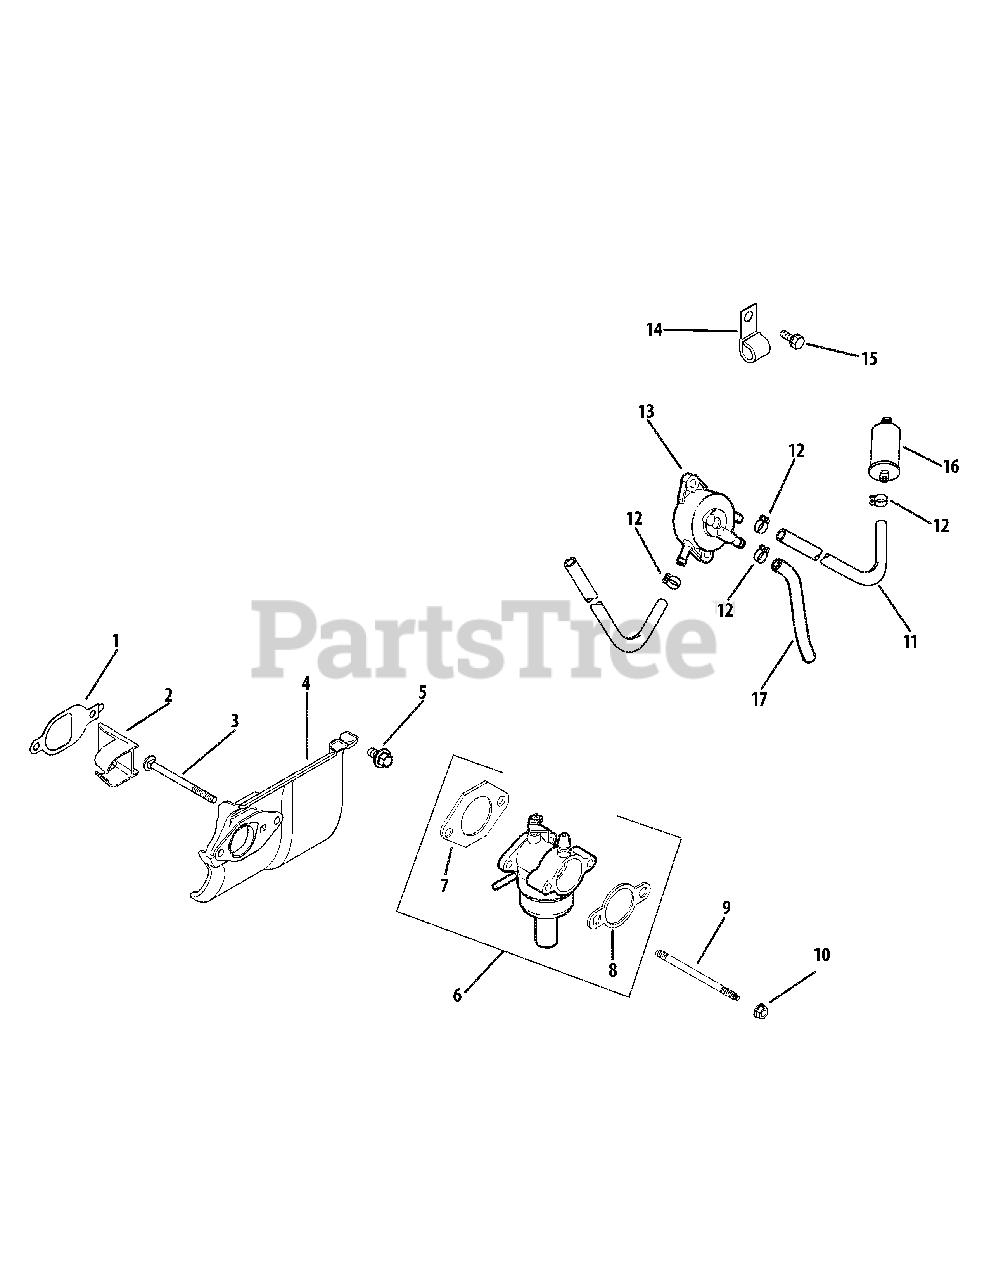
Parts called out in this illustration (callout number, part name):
1	Heat Deflector Gasket
2	Intake Port Insert
3	Carburetor Stud
4	Heat Deflector Kit
5	Flg Screw, M6 x 1.0 x 20
6	Carburetor Kit
7	Carburetor Gasket
8	Air Cleaner Base Gasket
9	Stud, M6 X 1.0 X 100
10	Flg Nut, M6 X 1.0
11	Fuel Line, 24"
12	Spring Hose Clamp, 1/2"
15	Thrd Frm Screw, M4 X 0.7 X 10
16	Fuel Filter
